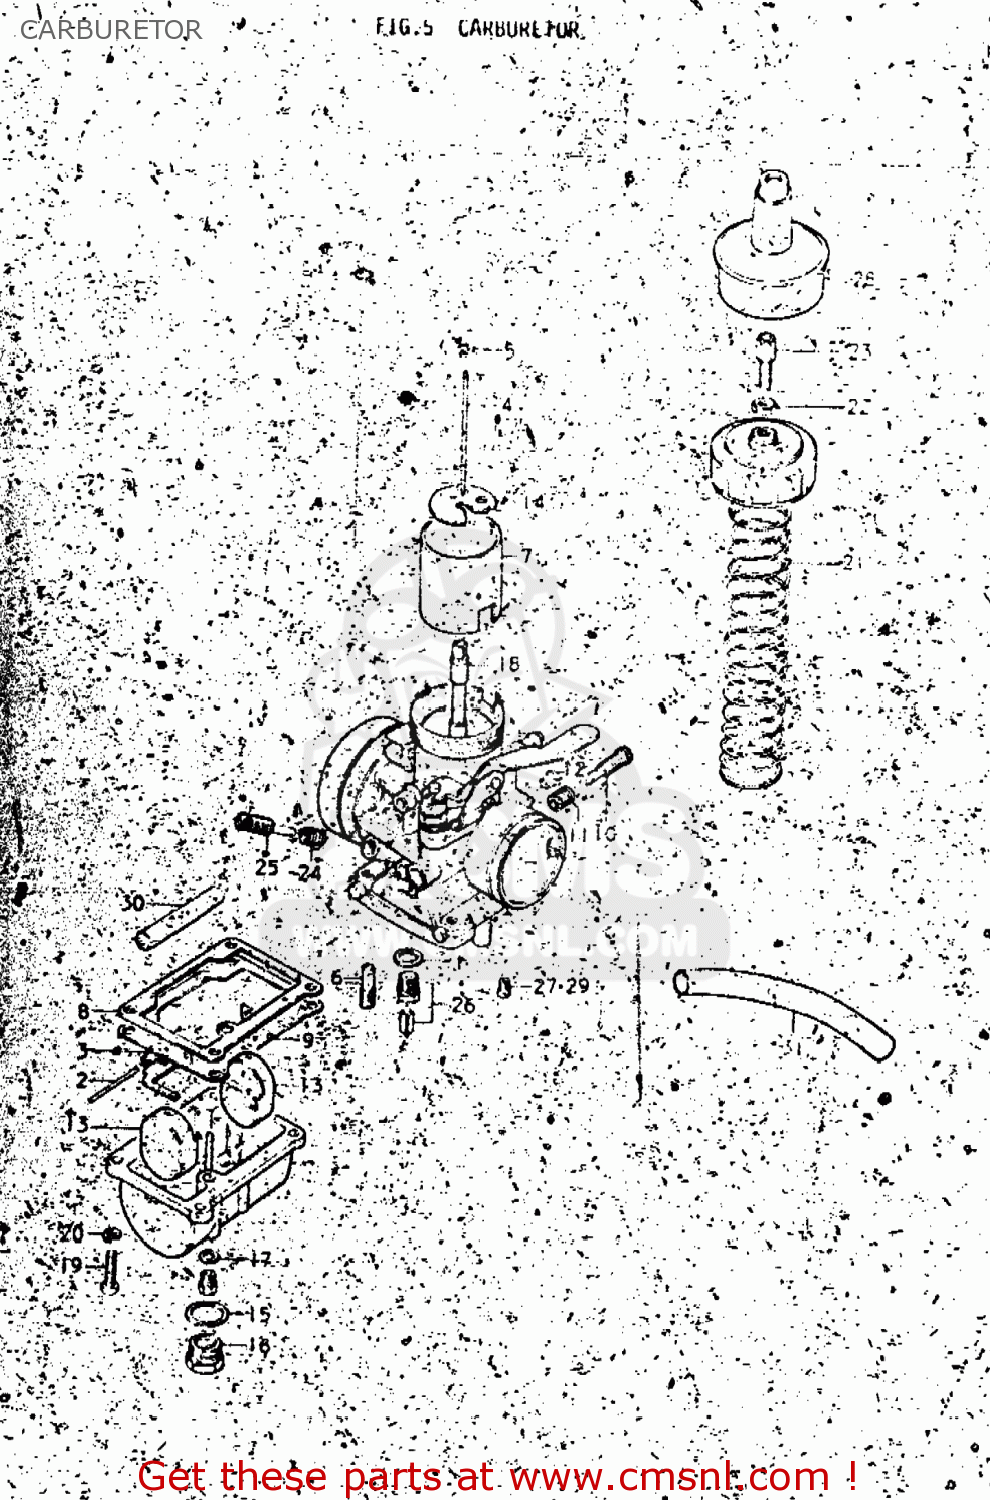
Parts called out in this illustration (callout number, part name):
0	CARBURETOR ASSEMBLY
1	GASKET,MAIN JET HOLDER (NAS)
2	PIN,FLOAT
3	ARM,FLOAT
4	NEEDLE JET
5	CLIP
6	JET,PILOT(40)
7	VALVE,THROTTLE
8	GASKET,FLOAT CHAMBER
9	PLATE
10	ADJUSTER
11	SPRING,THROTTLE SCREW
12	NUT, STOP SCREW
13	FLOAT
14	PLATE,THROTTLE VALVE
15	GASKET,DRAIN PLUG
16	PLUG
17	RING
18	JET,NEEDLE
19	SCREW
20	LOCK WASHER
21	SPRING
22	NUT
23	ADJUSTER,CABLE
24	SPRING
25	SCREW,PILOT AIR
26	VALVE ASSY,NEEDLE
27	JET
28	CAP
29	JET
30	HOSE
31	HOSE
